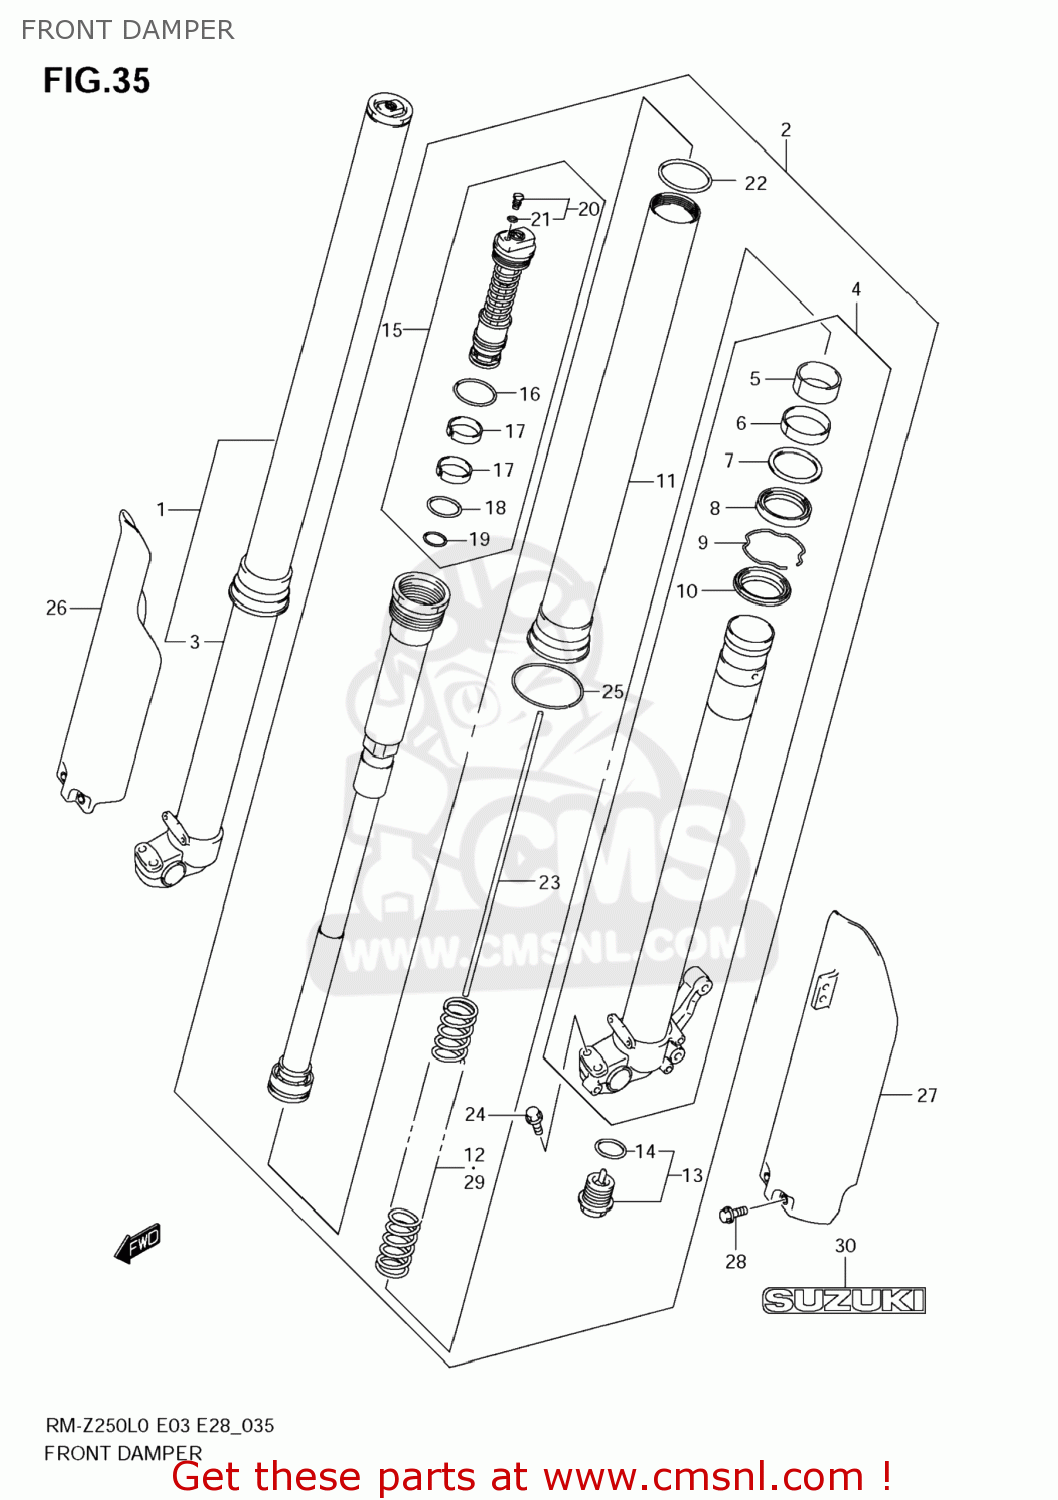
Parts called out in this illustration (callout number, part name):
1	DAMPER ASSY,FR FORK,R
2	DAMPER ASSY,FR FORK,L
3	TUBE,INNER,R
4	TUBE,INNER,L
5	BUSH
6	BUSH,GUIDE
7	SPACER,SEAL
8	SEAL,OIL
9	RING,OIL SEAL STOPPER
10	SEAL,DUST
11	TUBE,OUTER
12	SPRING,FR(K=0.47)
13	BOLT,CTR
14	O RING
15	BOLT,FORK
16	O RING
17	BUSH
18	O RING
19	O RING
20	BOLT,PLUG
21	O RING,PLUG
22	O RING
23	ROD,PUSH
24	BOLT
25	STOPPER,RING
26	PROTECTOR,FR FORK,R
27	PROTECTOR,FR FORK,L
28	BOLT(6X10)
29	SPRING,FR(K=0.45)
30	EMBLEM,SUZUKI
